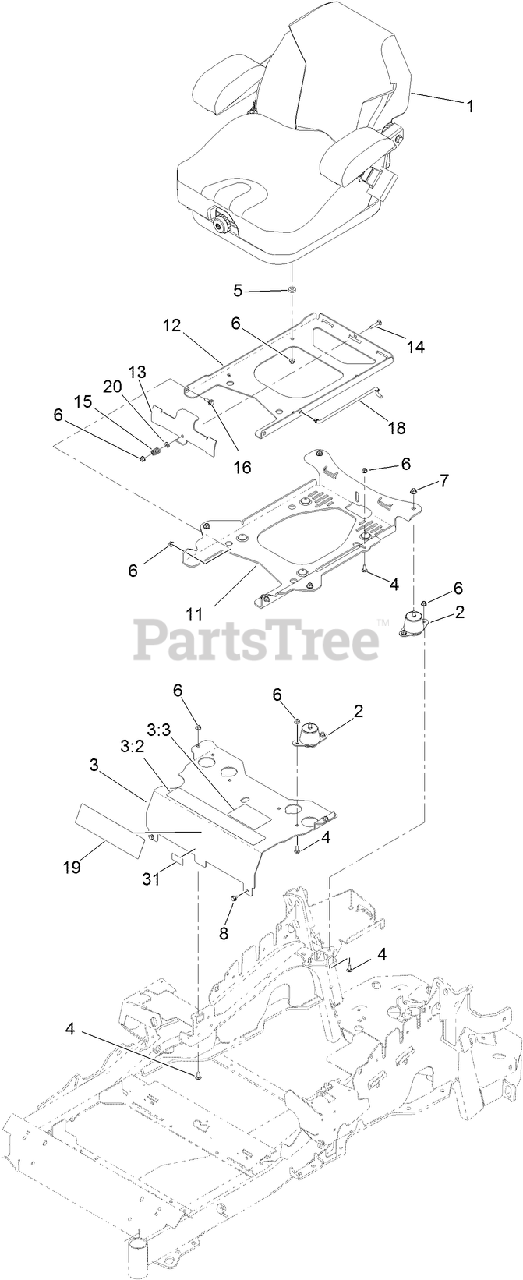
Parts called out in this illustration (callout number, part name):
1	SUSPENSION SEAT ASM
2	ISOLATOR-SEAT
3	SEAT MOUNT ASM
3:2	DECAL-CONSOLE
3:3	DECAL-SERVICE AID
4	SCREW-CARR
5	SPACER-PIN, MOUNTING
6	NUT-HF, NI
7	NUT-HF, NI
8	SCREW
11	PLATE-TILT, SEAT SUPPORT
12	PLATE-FRAME, SEAT
13	PLATE-LATCH, SEAT
14	BOLT-CARR
15	SPRING-COMPRESSION
16	SCREW-SHOULDER
18	ROD-PROP
20	WASHER-PLAIN
31	DECAL-EFI
